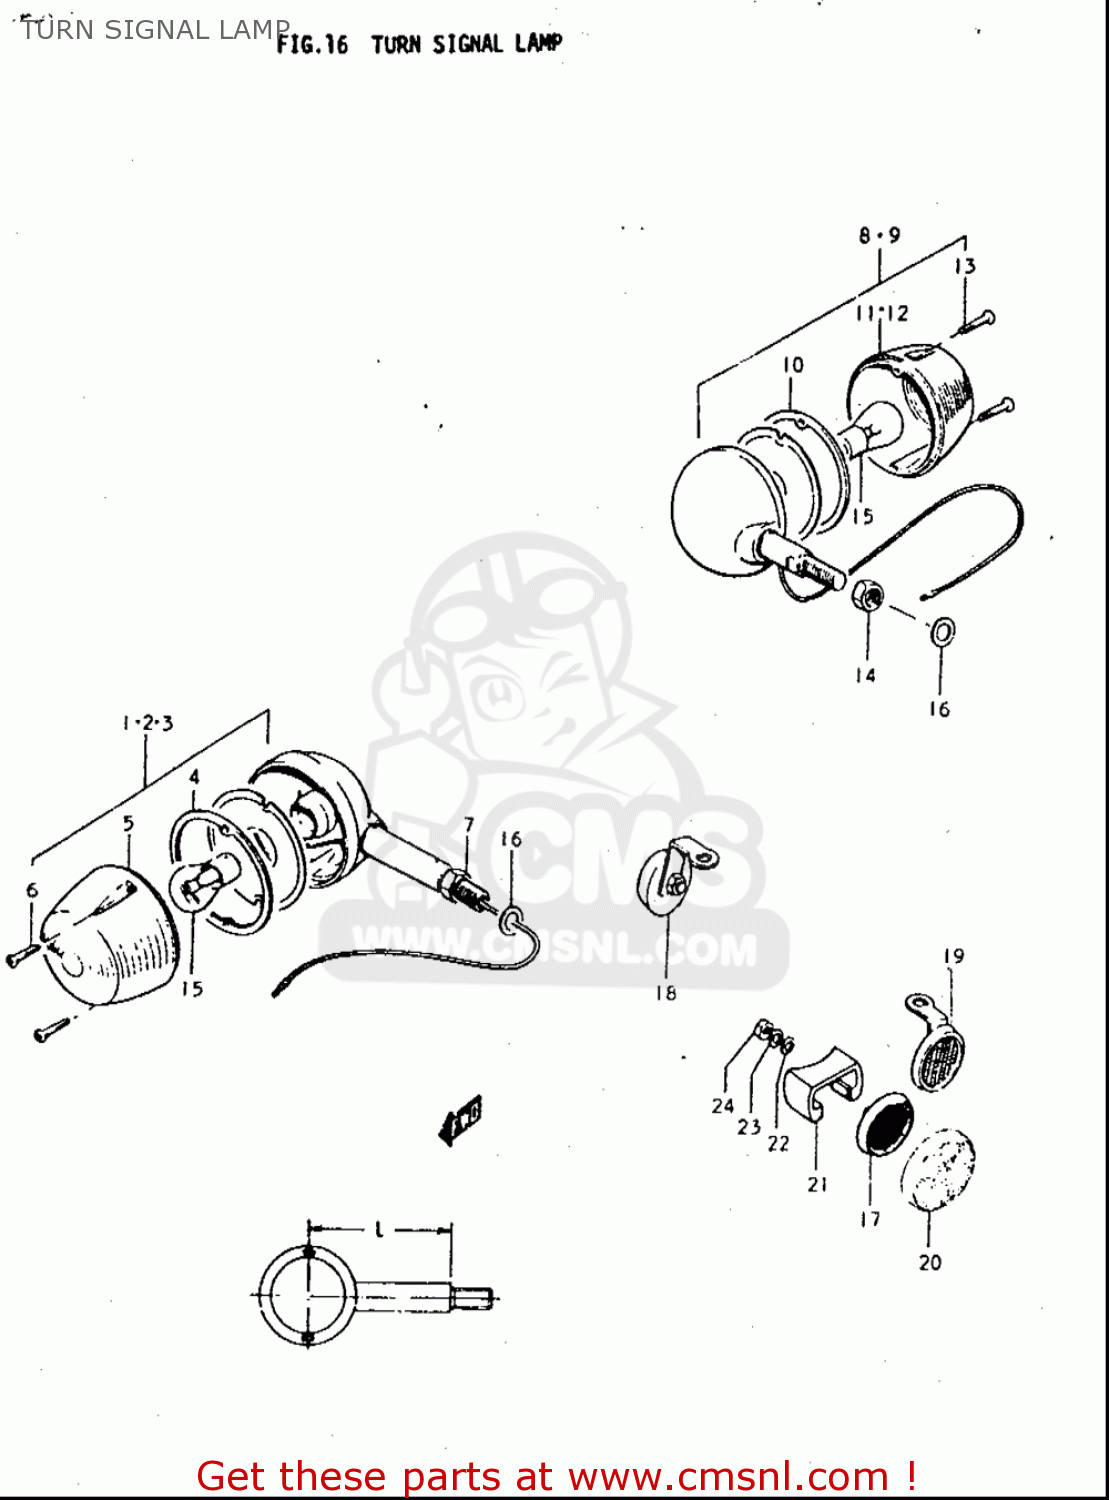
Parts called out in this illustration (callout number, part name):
1	LAMP ASSY,FR TURN SIGNAL
4	GASKET,TURNSIGNAL LENS (NAS)
5	LENS,TURNSIGNAL
6	SCREW
7	NUT
9	LAMP ASSY,RR TURNSIGNAL
10	GASKET,TURNSIGNAL LENS (NAS)
11	LENS,TURNSIGNAL
13	SCREW
14	NUT
15	BULB(12V23W,STANLEY,A4577A)
16	WASHER
20	REFLEX REFLECTOR,RR
22	WASHER
23	WASHER,LOCK
24	NUT
